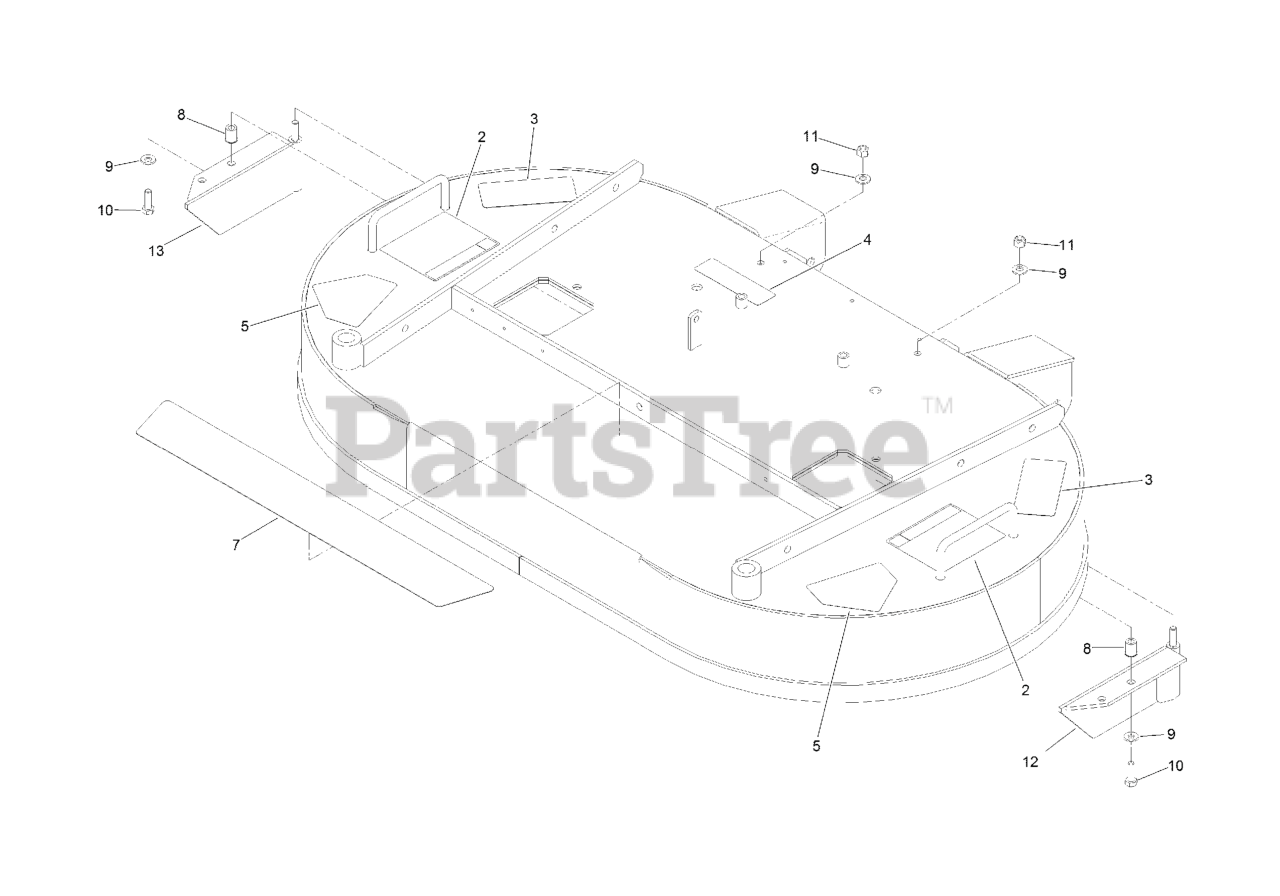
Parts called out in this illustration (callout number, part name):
2	DECAL-HEIGHT ADJUST, CUTT
3	DECAL-TORQUE, BLADE BOLT
4	DECAL-COVER, MISSING
5	DECAL-DANGER
7	PAD-SKID, ANTI
8	NUT-CLINCH
9	WASHER-SPRING
10	SCREW-HH
11	NUT-LOCK, NI
12	BAFFLE-LH
13	BAFFLE-RH
